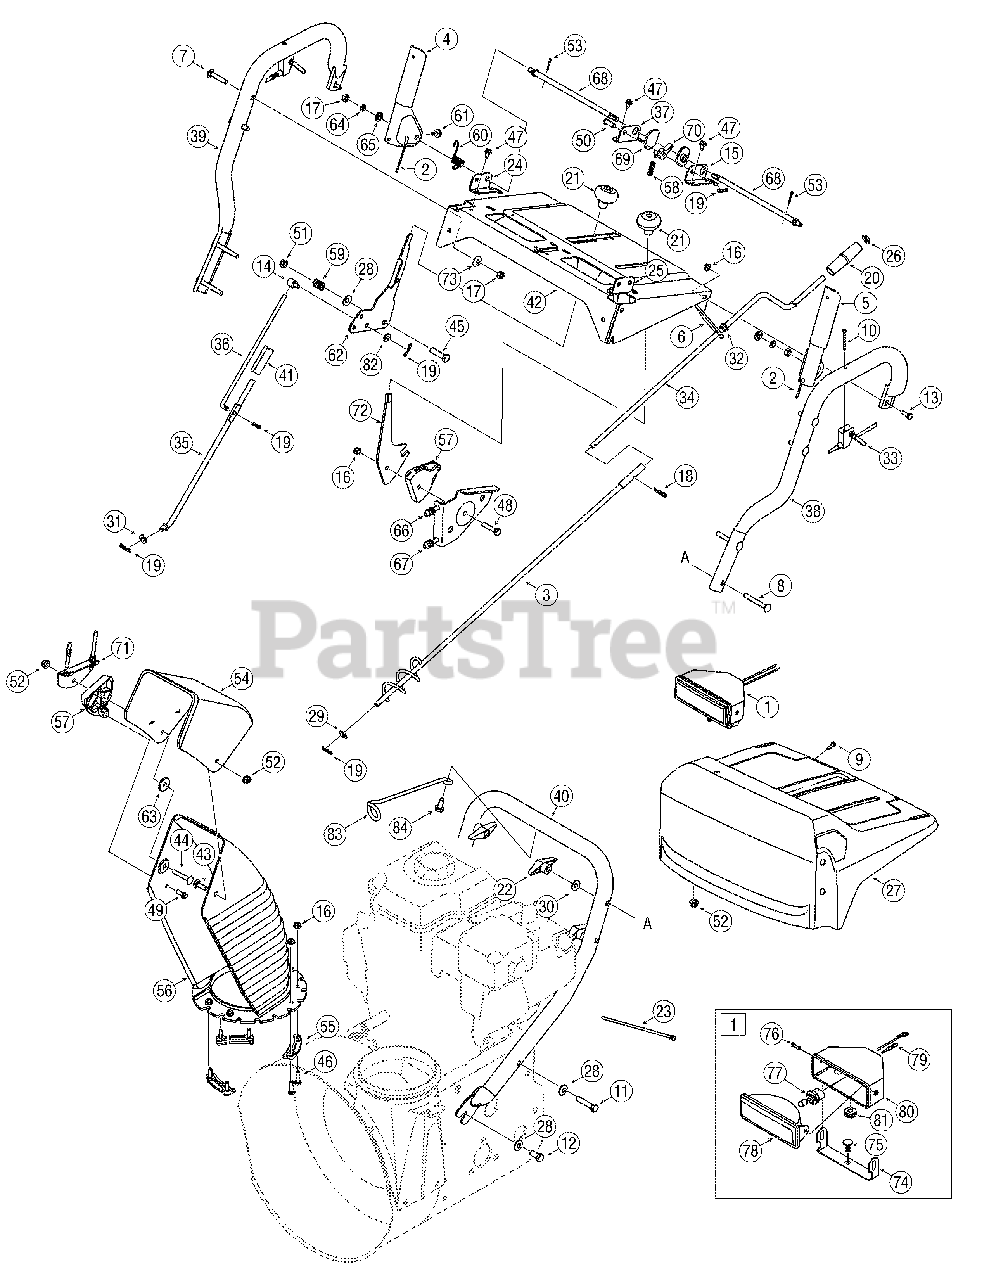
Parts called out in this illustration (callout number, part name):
1	Assembly, Light
2	Cable Ass’y, Auger/Drive
3	Crank, Chute, 26.0
4	Handle, Engage, RH
5	Handle, Engage, LH
6	Bracket, Chute Crank
7	Screw, Carr., 5/16-18 x 1.75
8	Screw, Carr., 5/16-18 x 2.5
9	Screw, #10-16 x .625
10	Screw, #10-24 x 1.75
11	Screw, Hex, 3/8-16 x 2.00
12	Screw, Hex, 3/8-16 x 1.00
13	Screw, Hex, 1/4-20 x .75
14	Ferrule, 5/16-18 x .312 Dia
15	Brkt., Handle Support - LH
16	Nut, Hex Flange, 1/4-20
17	Nut, Hex Lock, 5/16-18 GR5
18	Pin, Internal Cotter
19	Pin, Internal Cotter
20	Knob, Crank
21	Knob, Shift
22	Knob, Wing, 5/16-18
23	Tie, Cable
24	Brkt., Handle Support - RH
25	Brkt., Handle Support - LH
26	Cap, Push, 3/8
27	Panel, Handle
28	Wash, Bell, .375 x .87 x .063
29	Wash,Fl., .375 x .738 x .063
30	Wash, Bell, .34 x .872 x .06
31	Wash, Fl, .344 x .688 x .065
32	Bushing, Plastic, .38 ID
33	Cable Assembly, Trigger
34	Rod, Chute Crank
35	Rod, Lower Shift
36	Rod, Upper Shift
37	Brkt., Handle Support - RH
38	Handle, Upper LH
39	Handle, Upper RH
40	Handle, Lower
41	Connector, Shift Rod
42	Panel, Handle
43	Screw, Carr, 5/16-18 x 1.0
44	Screw, Carr., 5/16-18 x 1.75
45	Screw, Hex, 3/8-24 x 1.5
46	Screw, Hex, 1/4-20 x 1.0
47	Screw, Hx, 1/4-20 x .5
48	Screw, Hex, 5/16-18 x 1.5
49	Screw, Hx,1/4-15 x .75
50	Pin, Clevis, .312 x 1.0
51	Nut, Insert, 3/8-24
52	Nut, Flnge Lk, 5/16-18
53	Pin, Cotter, 3/32 x .75
54	Chute, Upper, 6.0
55	Flange Keeper, Chute
56	Chute, Lower
57	Cbl. Guide, Chute Tilt
58	Spring, Compression
59	Spring, Compression
60	Spring, Torsion
61	Bumper, Rubber
62	Handle, Shift
63	Wash, Fl, .344 x 1.125 x .12
64	Washer, Lock, 5/16
65	Wash, Fl, .35 Sq x .72 x .134
66	Cable, Chute Control, 66"
67	Cable, Chute Control w/Clip,
68	Rod, Cam
69	Cam, Handle Lock
70	Pawl, Handle Lock
71	Bracket, Cable
72	Handle, Chute Tilt
73	Washer, Flat, .349 x .879 x .063
74	Bracket, Mount, Lamp
75	Bolt, Carriage, 5/16-18 x .750
76	Screw, M4 x .7
78	Housing, Lamp
79	Harness
80	Housing
81	Grommet
82	Wash, Fl, .344 x .750 x .120
83	Cable Guide
84	Screw, 5/16-18 x .750
